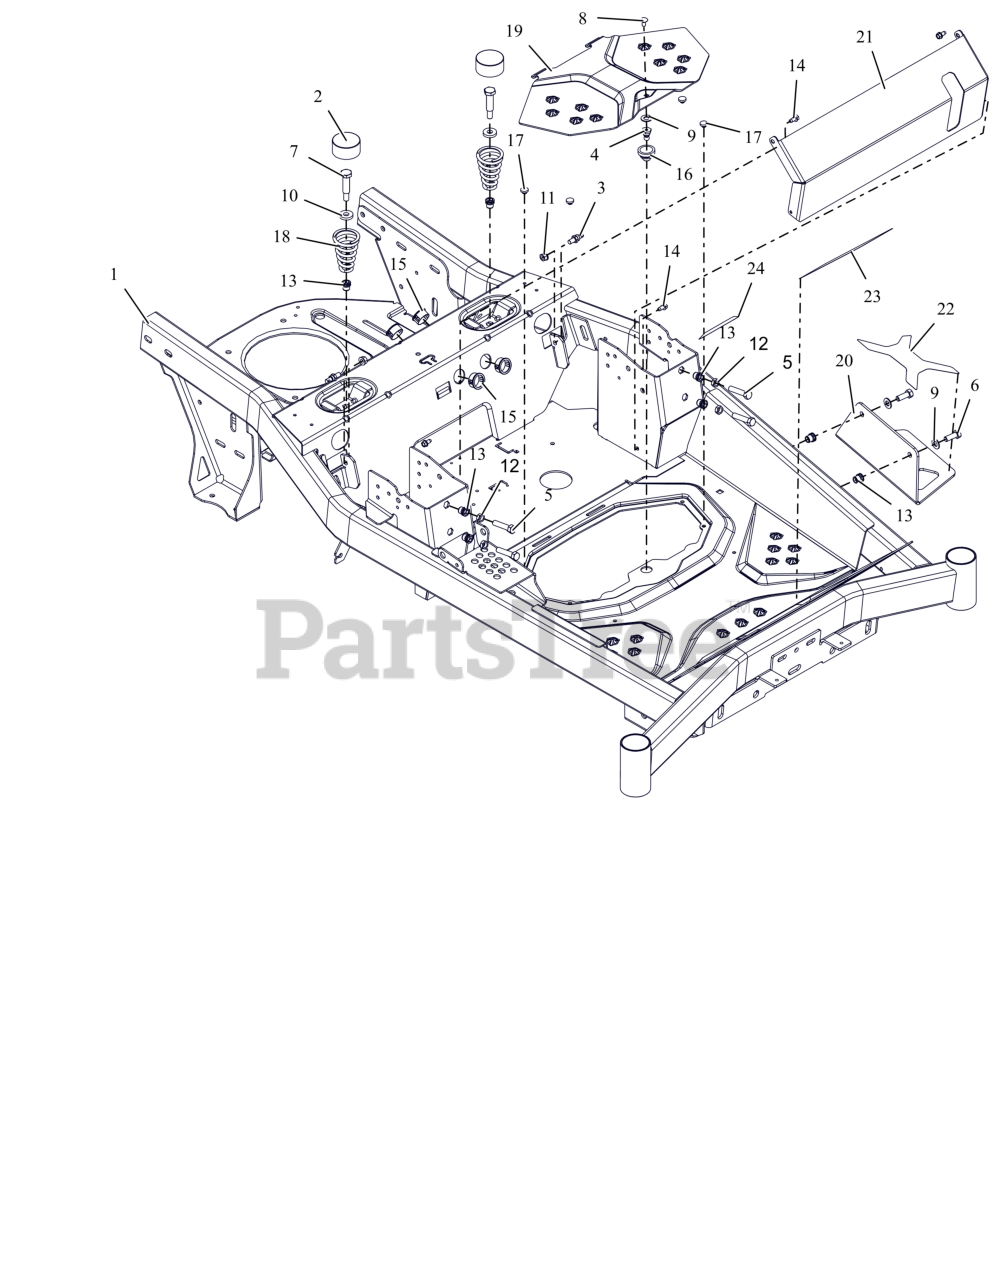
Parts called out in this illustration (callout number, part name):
1	KIT,ARIENS FRAME W/ DECALS
2	HUB CAP
3	COUPLER, DAMPER MOUNT
4	STUD, BALL FEMALE .250-20 THREAD
5	BLT, HEX .38-16X1.75F G5 ZCC
6	BLT, HEX .38-16X1.00 G8ZCCEP30
7	BLT-SHLDR .50X1.50 .375-16 ZCC
8	BLT, RHSSN.25-20X.500 G5 ZCC
9	WSHR,FLT .406X.812X.065 ZCC
10	WSHR, FLT .406X1.00X.188 ZCC
11	NUT-LK-TOP-FLG .312-18 GF ZCC
12	NUT-JAM .375-16 G2 ZCC
13	NUT,THD,INSERT .38-16 ZC120
14	SCR-TAP .25-20X.50 HWH ZCC
15	BSHG, PANEL SNAP .937X1.11X.56
16	COUPLING, RUBBER PUSH-IN
17	BUMPER GROMMET
18	SPRING, SEAT
19	KIT, ARIENS ACCESS PLT W/DECAL
21	PLATE- FRONT KICK
22	GRIP- TAPE - STEP -ARIENS
23	GRIP- TAPE - FOOTPLATE L
24	GRIP- TAPE - FOOTPLATE R
